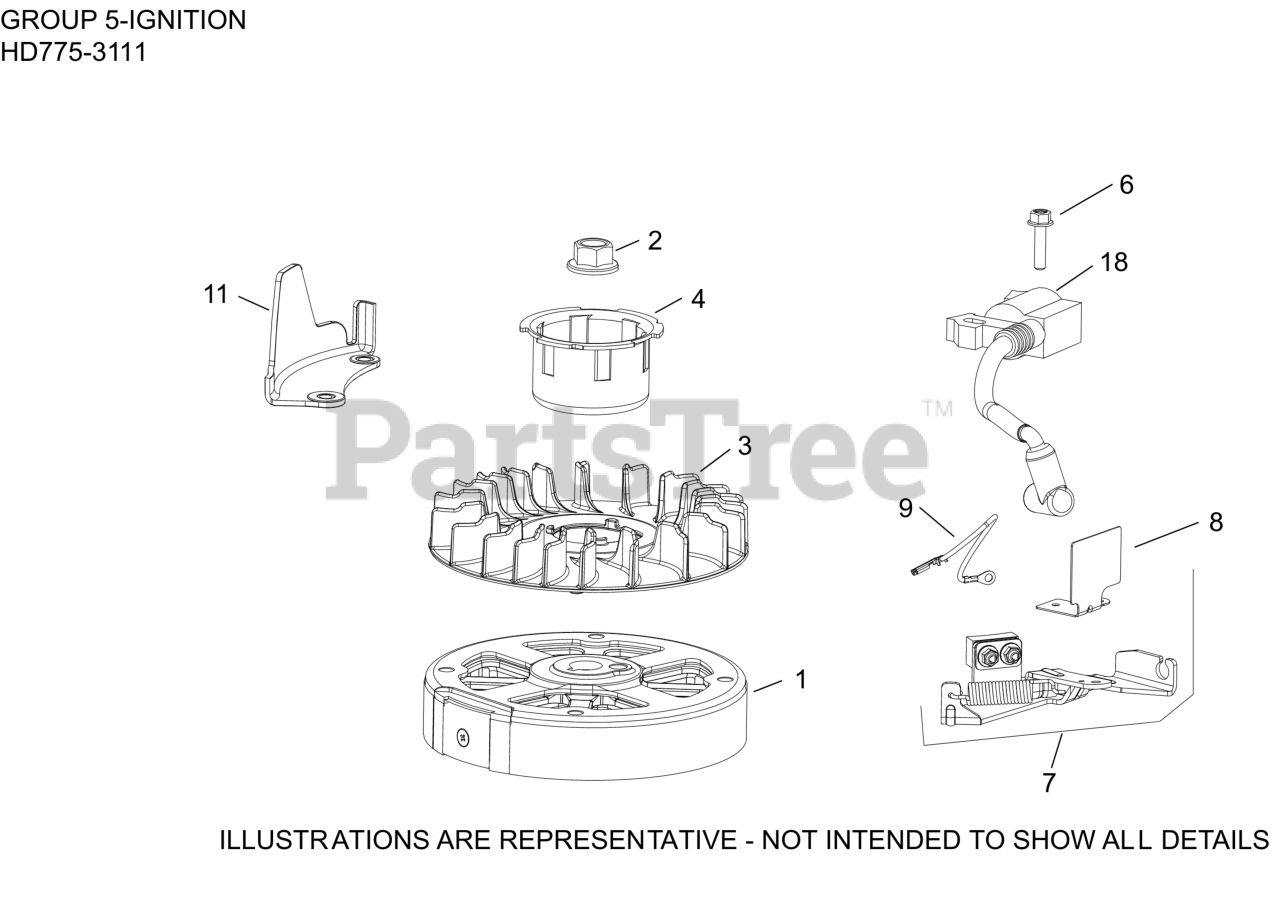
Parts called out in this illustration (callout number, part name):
1	FLYWHEEL ASSEMBLY
2	NUT, FLYWHEEL (W/SERRATIONS)
3	FAN, FLYWHEEL
4	CUP, STARTER DRIVE
6	SCREW, M6 X 25-(#25086436S)
7	BRAKE ASSEMBLY
8	GUARD, BRAKE - USE 14 314 30-S
9	LEAD, KILL (BRAKE TO IGN. MODULE)
11	GUARD, FINGER
18	MODULE IGNITION CAST IRON FLYWHEEL
